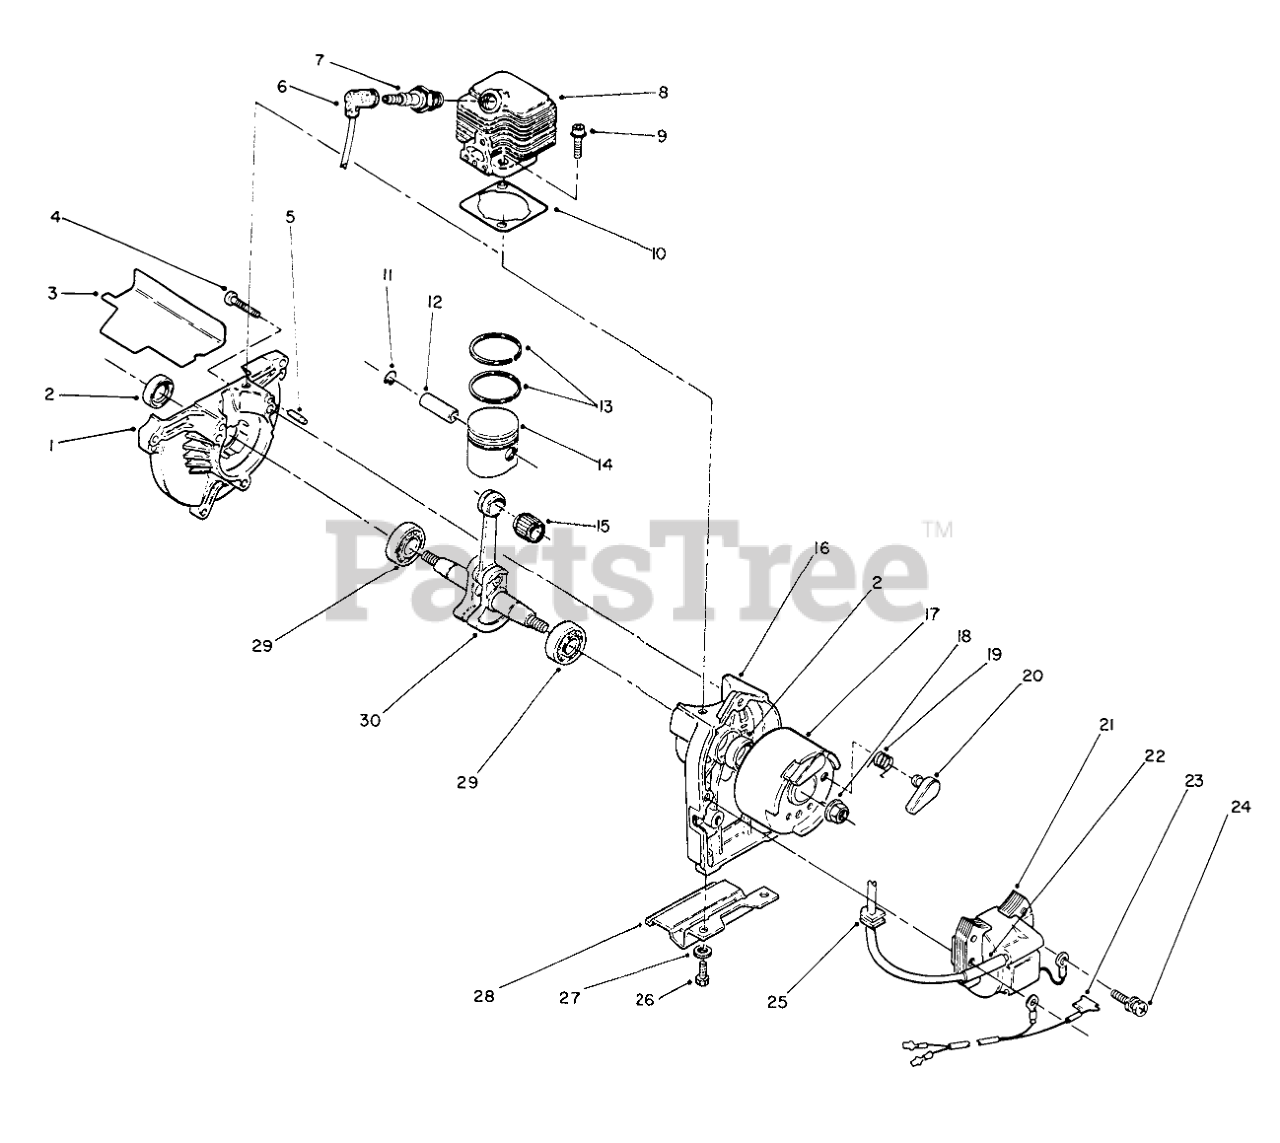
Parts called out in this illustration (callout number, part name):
1	DRIVE CASE
2	OIL SEAL
3	BAFFLE GASKET
4	Screw
6	PLUG BOOT
7	SPARK PLUG (NGK)
8	CYLINDER
9	FLANGE BOLT
10	CYL GASKET
11	PISTON PIN CLIP
12	Pin-Piston
13	TOP RING
14	Piston Assembly(Incl. Ref. #12)
15	NEEDLE BEARING
16	STARTER CASE
17	Flywheel Assembly(Incl. Ref. #19 & 20)
19	RETURN SPRING
20	RATCHET
21	IGNITION COIL
23	Wire Assembly
24	BOLT AND WASHER
25	GROMMET
26	M6 X 1 X 1/2 MWH SCREW
27	WASHER-LOCK
28	STAND SUPPORT
29	BEARING
30	CRANKSHAFT ASSEMBLY
